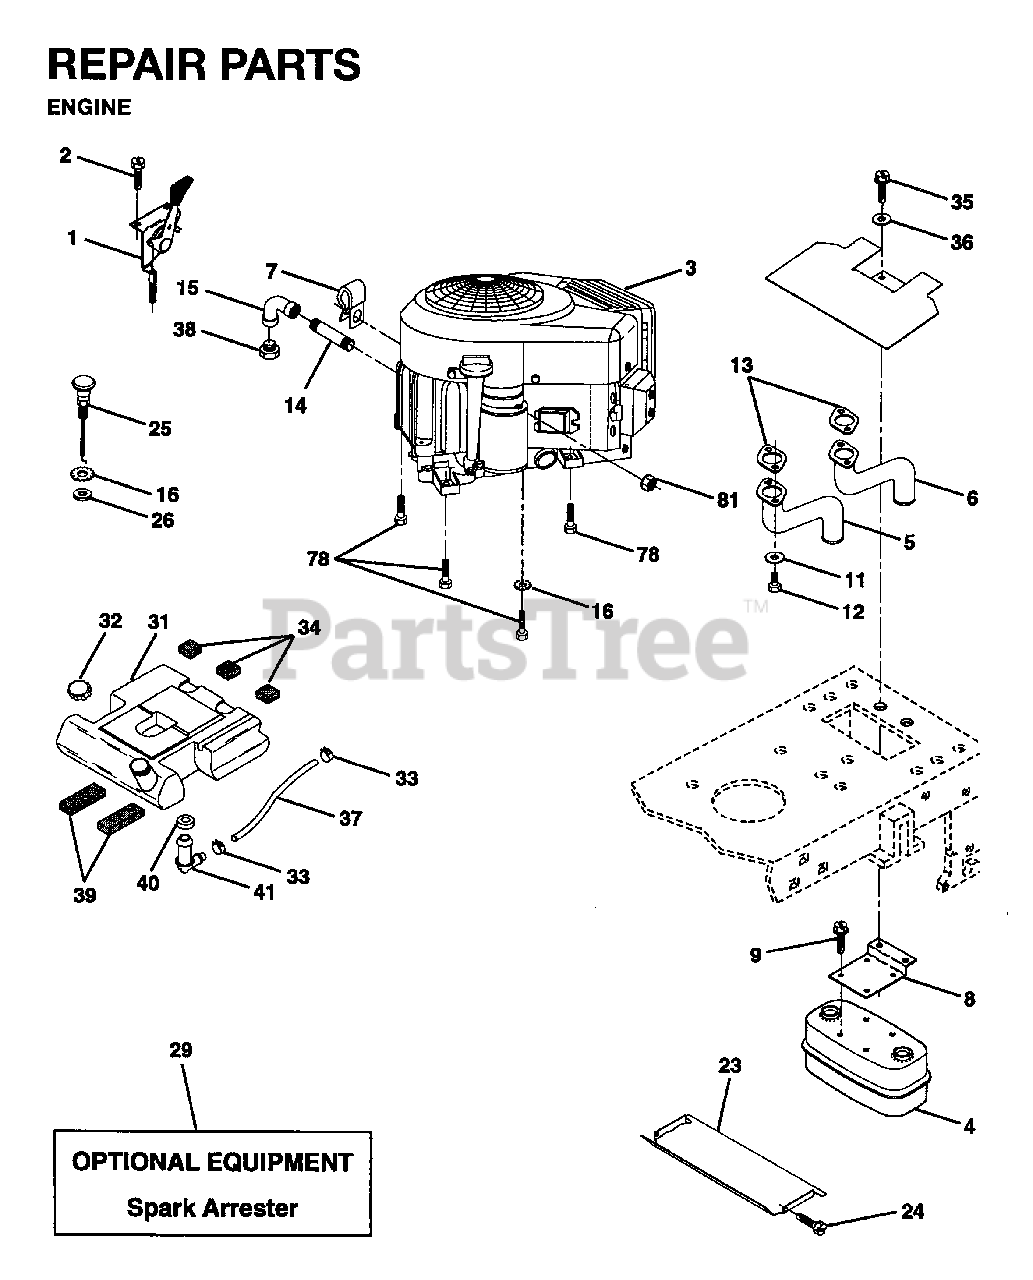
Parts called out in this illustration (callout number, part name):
1	THROTTLE CONTROL
2	BOLT
4	MUFFLER
5	TUBE ASSY EXH LH
6	TUBE ASSY EXH RH
8	BRACKET MUFFLER
9	BOLT
14	PIPE NIPPLE LT
15	ELBOW
16	WASHER, LOCK 3/8
23	HEAT SHIELD
25	CHOKE CONTROL
26	NUT
29	ARRESTER SPARK (OPTIONAL)
31	FUEL TANK REAR YT/GT
32	FUEL CAP
33	HOSE CLAMP
34	PAD-SPACER LT
35	BOLT
37	FUEL LINE
39	PAD IDLER TI
40	BUSHING OUTLET T
41	STEM FUEL TANK
78	BOLT
81	NUT.CROWNLOCK.1/4
